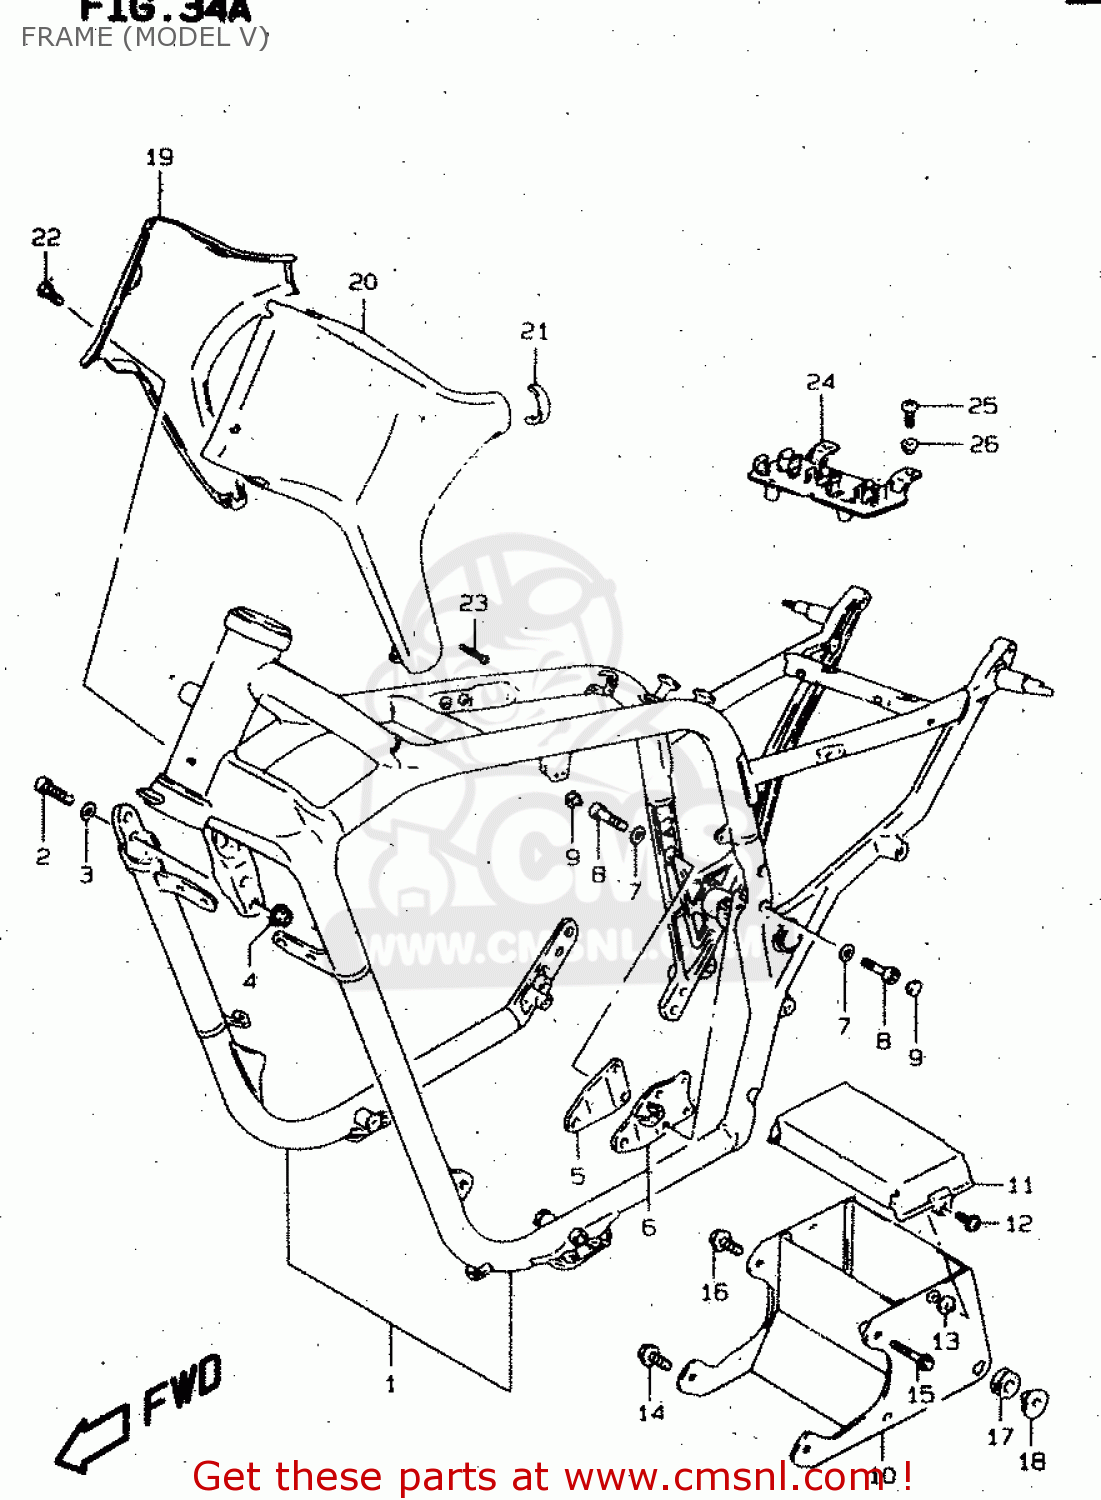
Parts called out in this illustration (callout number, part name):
1	FRAME SET
2	BOLT(10X33)
3	WASHER
4	NUT 10MM
5	PLATE,ENG MTG NO.4,R
6	PLATE,ENGINE MOUNT NO.4,L
7	WASHER
8	BOLT(8X32)
9	CAP(OD:14.5)
10	HOLDER,BATTERY
11	COVER,BATTERY
12	SCREW(5X12)
13	WASHER
14	BOLT
15	BOLT
16	BOLT(8X40)
17	CUSHION
18	BUSH
19	COVER COMP,FRAME HEAD
20	COVER,FRM.HD.,
21	PROTECTOR,FRAME HEAD COVER
22	SCREW 6X10
23	SCREW
24	HOLDER,COUPLER
25	SCREW
26	WASHER
